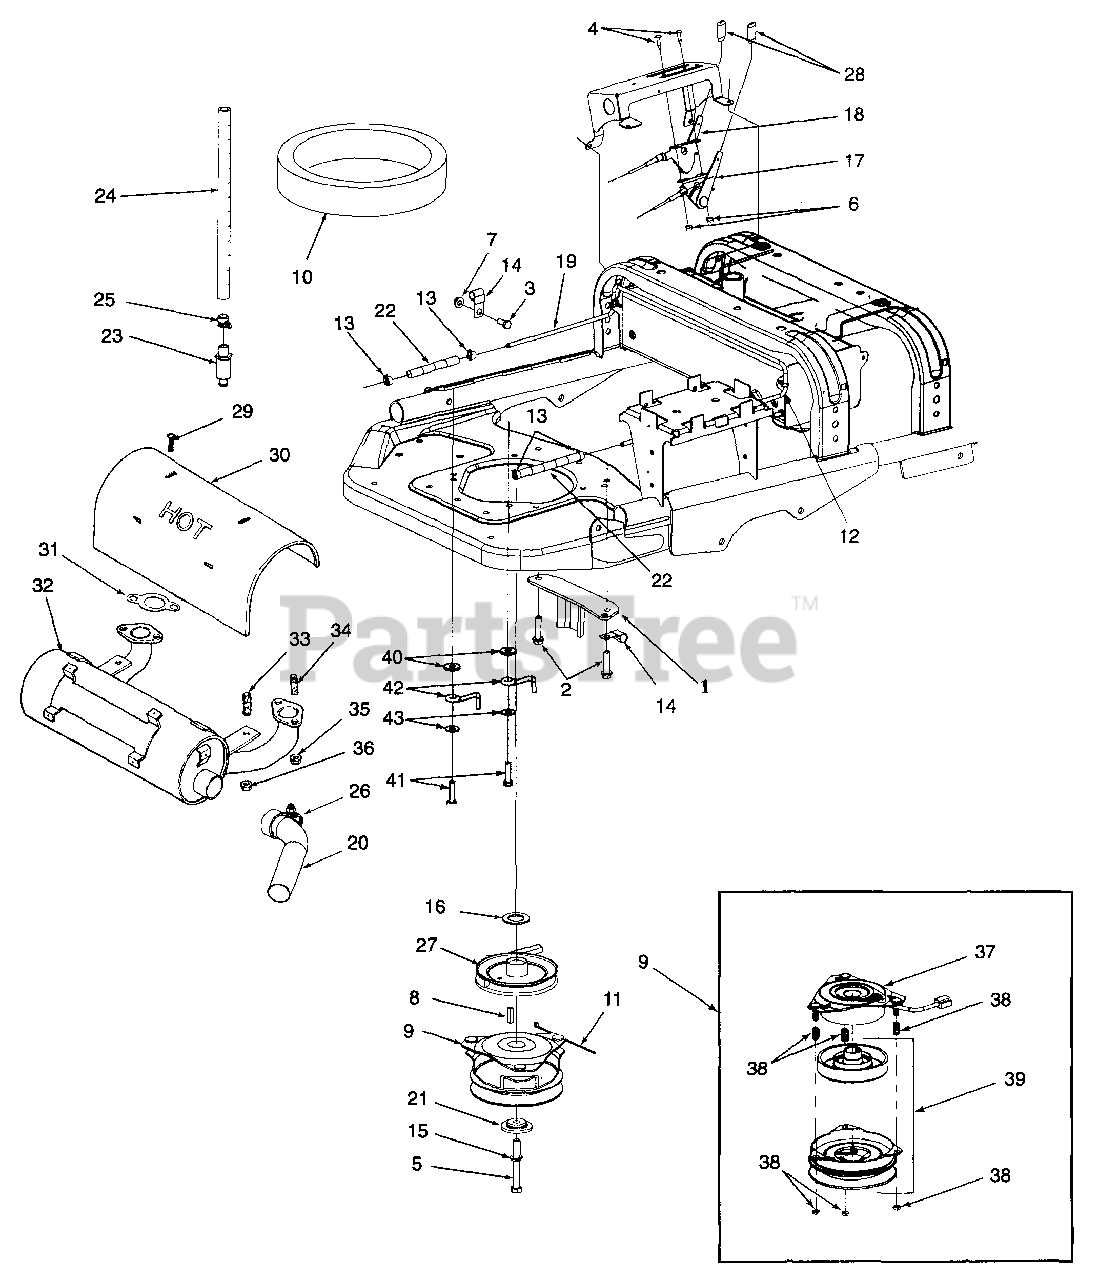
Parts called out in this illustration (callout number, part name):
3	Screw, Hex Cap 5/16-18 x .75 GR5
4	Screw, Phil. Pan Hd, 10-24 x .75
5	Screw, Hex Cap 7/16-20 x 3.25 GR5
6	Nut, Hex Lock, #10-24
7	Nut, Hex Flange Lock, 5/16-18
8	Key, Square, 1/4 x 1.0
9	Clutch Assembly, PTO
10	Seal Ring, Foam Gasket
11	Cable Tie
12	Clip, Retainer
13	Clamp, Hose
14	Clip, Cable
15	Washer, Lock, 7/16
16	Washer, Flat, 1.0 x 1.75 x .10
17	Cable, Choke Control
18	Cable, Throttle Control
19	Fuel Line
21	Spacer, PTO Clutch
22	Fuel Line Hose 5" Length
23	Drain, Oil
24	Extension Hose, Oil Drain 13" Lg
25	Cap, Oil Drain
26	Clamp, Muffler Exhaust Tube
27	Pulley, Transmission Drive
29	Screw, Sems Drill, #8-18 x 9/16
30	Duct, Heat Shield
31	Gasket, Exhaust
32	Muffler
33	Stud, Thread Rolling
34	Stud, Exhaust Manifold M8 x 1.25 x 20
35	Nut, Muffler Mounting, M8 x 1.25
36	Nut, Hex Flange, M6 x 1.0
37	Field Assembly
38	Kit, Spring and Nut
39	Armature/Rotor Assembly
40	Washer, Flat
41	Screw, Hex Wsh. Hd. Tap.
42	Rod, Rear Bolt Retainer
43	Washer, Flat
